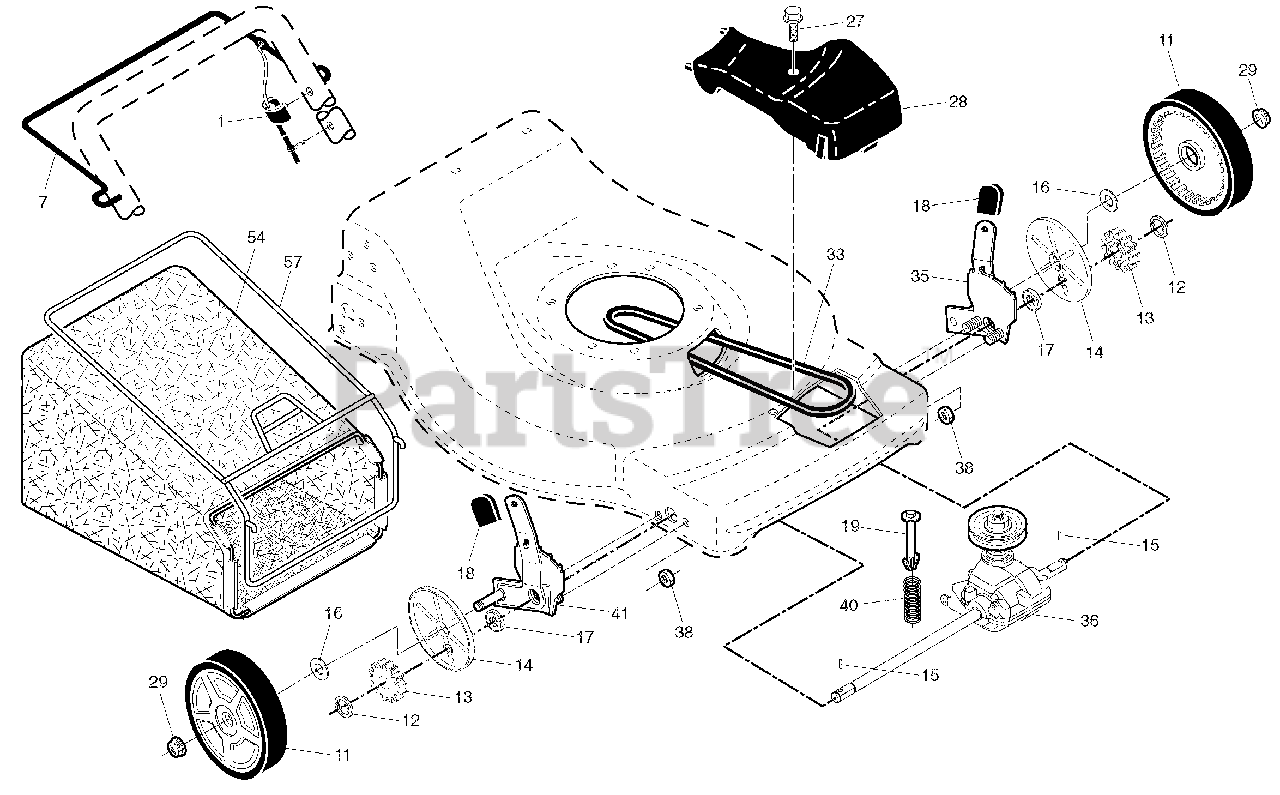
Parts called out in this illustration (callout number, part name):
1	CABLE, DRIVE CONTROL
7	Control Bar, Drive
11	WHEEL AND TIRE ASSEMBLY-FRONT
14	Dust Cover
15	Pawl, Drive
16	Washer, Flat 3/8
17	WHEEL BEARING
18	Selector Knob
19	Retainer, Spring
27	Pan Head Tapping Screw #10-24
28	DRIVE COVER
29	Nut, Hex
33	DRIVE BELT
35	Kit, Wheel Adjuster, LH
36	Gear Case Assembly, Complete
38	Locknut, Hex 1/4-20
41	HEIGHT ADJUSTOR
57	BAG FRAME
